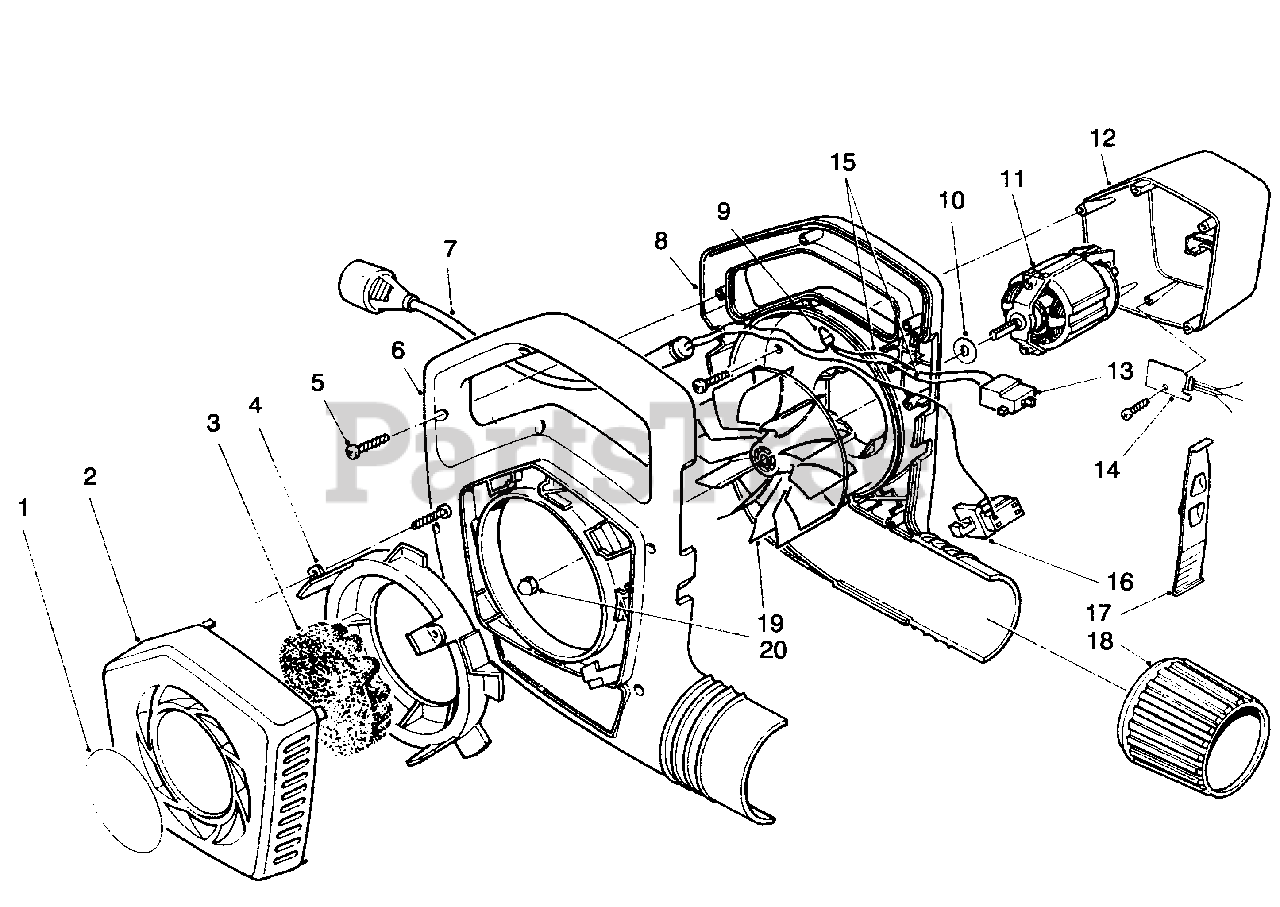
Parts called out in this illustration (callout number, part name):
1	Decal-Cover
2	Cover-Intake
3	Foam-Center
4	Ring-Coupling
5	Screw-Self Tapping
6	Housing-Blower, R.H.
7	Cord-Power Supply
8	Housing-Blower, L.H.
9	Connector-Wire
10	Washer-Impeller
11	Motor-Blower
12	Cover-Motor
13	Switch-2 Speed
14	Diode Assembly
16	Switch-Interlock
17	Switch-Cam, 2 Speed
18	Collar-Output
19	Impeller
20	Nut-Cap, Locking
